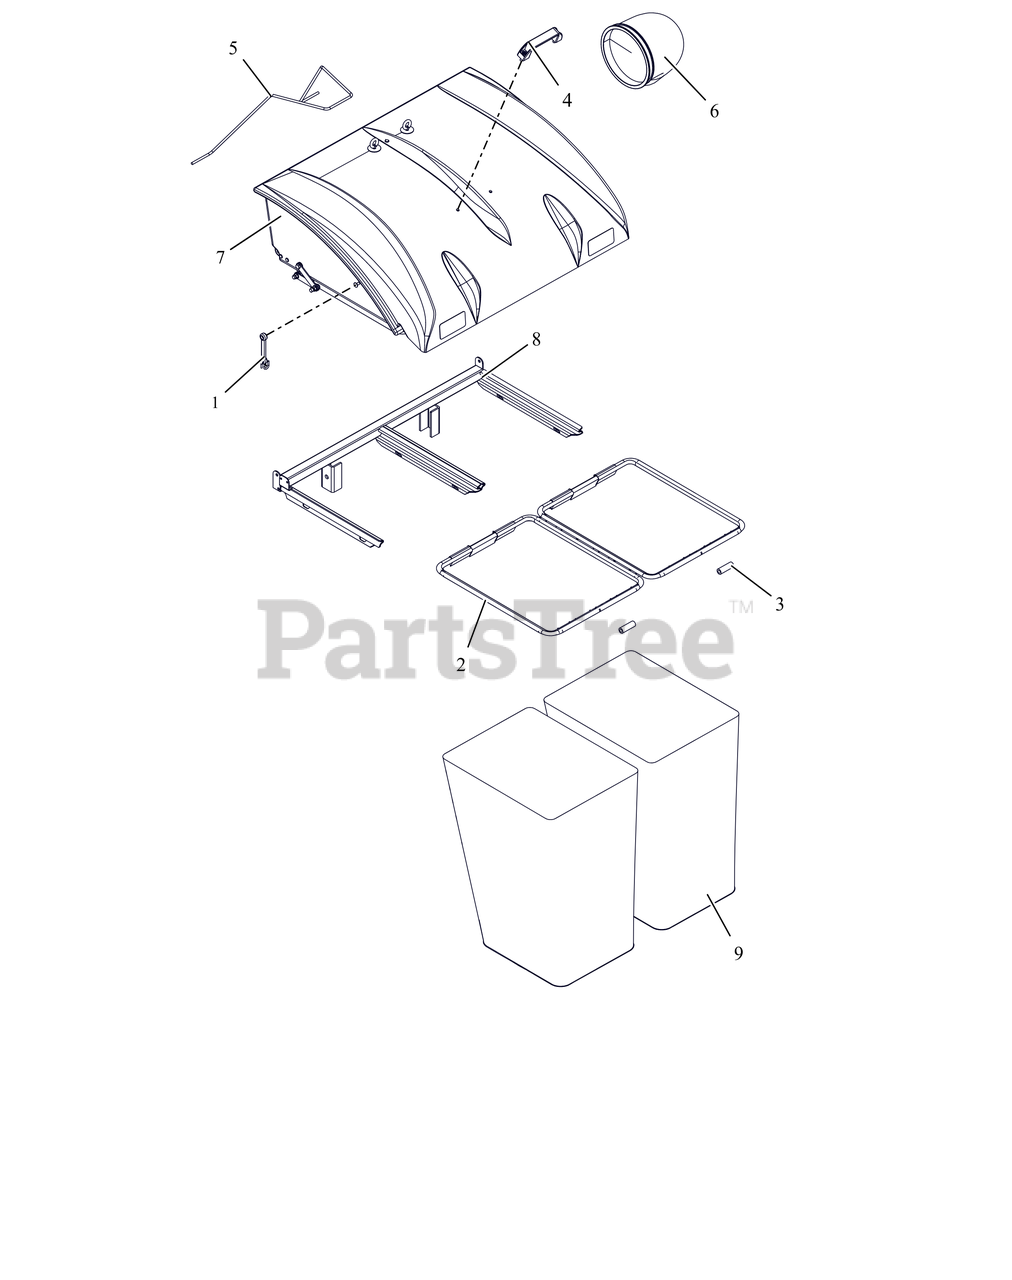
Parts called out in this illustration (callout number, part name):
1	RUBBER HOOD STRAP
2	FRAME, BAG
3	HOSE, VINYL
5	ROPE, BAGGER RELEASE
6	ELBOW, PECO 3 BAG BAGGER
7	HOOD ASM PECO 2 BAG
8	FRAME ASM PECO 2 BAG
9	BAG, MESH
